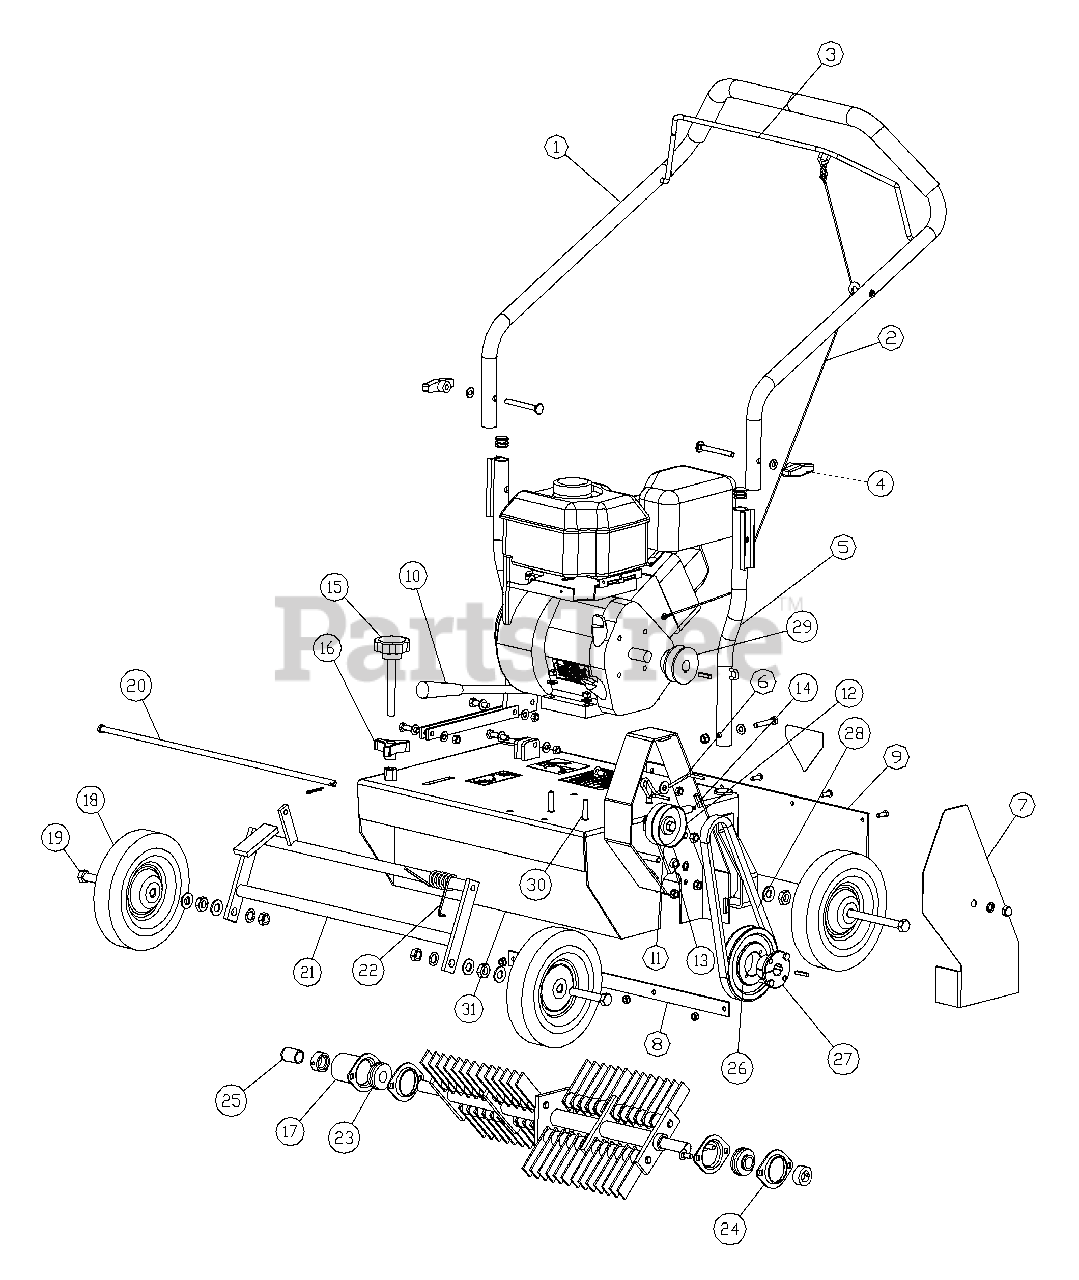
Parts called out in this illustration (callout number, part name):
1	Handle Assembly.
2	Clutch Cable Assembly.
4	Knob, Folding Handle Kit
5	Lower Handle Assembly.
6	Belt Keeper Kit
7	Belt Guard Kit
8	Deflector Kit
9	Deflector, neoprene
10	Depth Lever Assembly.
11	Idler Assembly Kit
12	Pulley, idler 2 3/4 OD
13	Mounting Arm, idler pulley
14	Spring, Clutch rod
15	Depth Adjustments Knob
16	3 - pronged lock depth knob
17	Rotor guard
18	Wheel, 8 x 1 3/4, ball bearing
19	Bolt kit for wheel
20	Lift Arm Rod Kit
21	Lift Arm Assembly Kit
22	Torsion spring
23	Bearing, 3/4 with locking collar
24	Stamping Kit
25	Rotor cap, 3/4 ID
26	V - Pulley, B-5.0 OD, tapered bore
27	Bushing kit
28	V - Belt, B-33, special
29	V - Pulley engine kit for 3/4 bore
30	Engine Bolt Kit
31	Deck, DT18C
33	Rear wheel, 10 x 2 3/4 ball bearing
